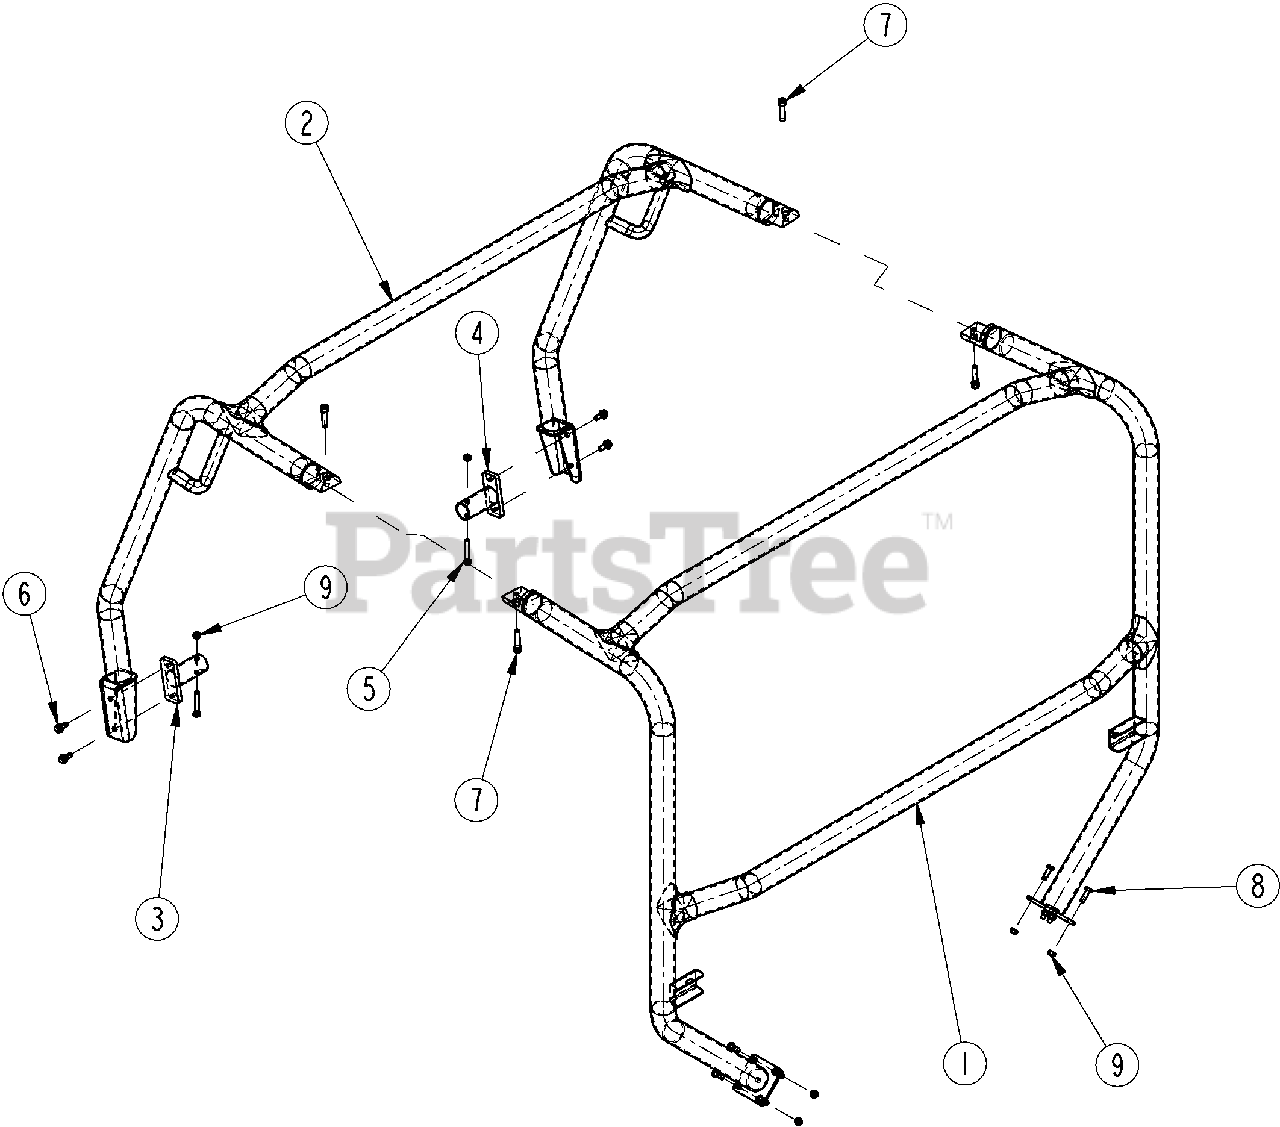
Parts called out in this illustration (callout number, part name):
1	WELDMENT, ACCESSORY BAR REAR
2	WELDMENT, ACCESSORY BAR FRONT
3	BAR MOUNT FRONT LH
4	BAR MOUNT FRONT RH
5	BOLT, HEX 5/16-18 X 2 GR5
6	HFS 5/16-18X3/4 GR5
7	HSHCS 3/8-16X1 1/2 Apply Loctite
8	BOLT, HEX 5/16-18X 1 GR5 Apply Loctite
9	NUT, NYLON LOCK 5/16-18 PLT
